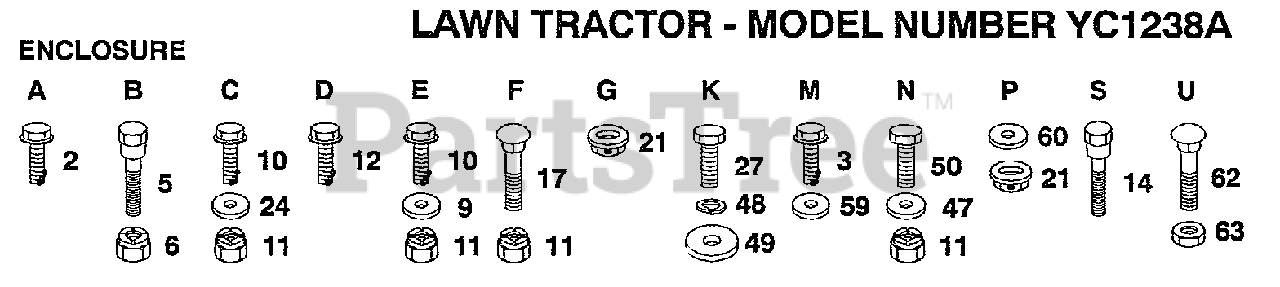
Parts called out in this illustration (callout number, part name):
2	SCREW
3	SCREW GTV
9	WASHER
12	SCREW LT
14	"BOLT,SHOULDER"
17	BOLT
21	PAL NUT LT
24	WASHER
27	BOLT
47	WASHER
48	LOCKWASHER
49	WASHER
50	BOLT
59	WASHER
60	WASHER PM
62	BOLT
